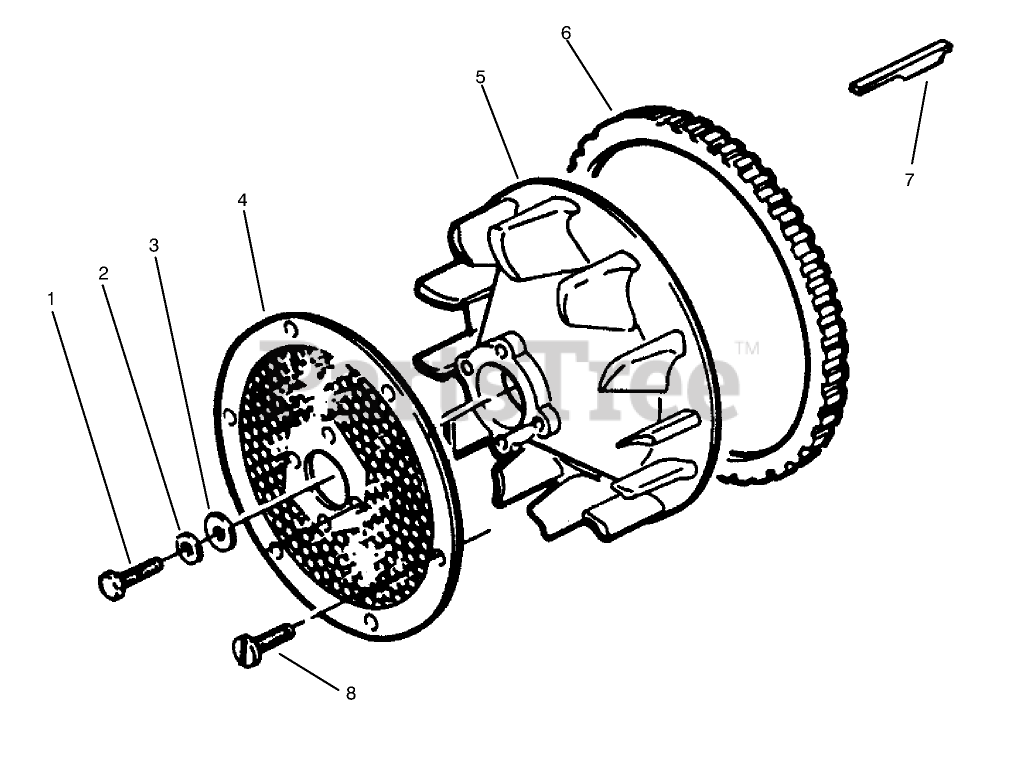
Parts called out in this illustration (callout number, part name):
2	WASHER-FLAT
3	WASHER-FLAT
4	SCREEN-AIR INLET
7	KEY-FLYWHEEL
